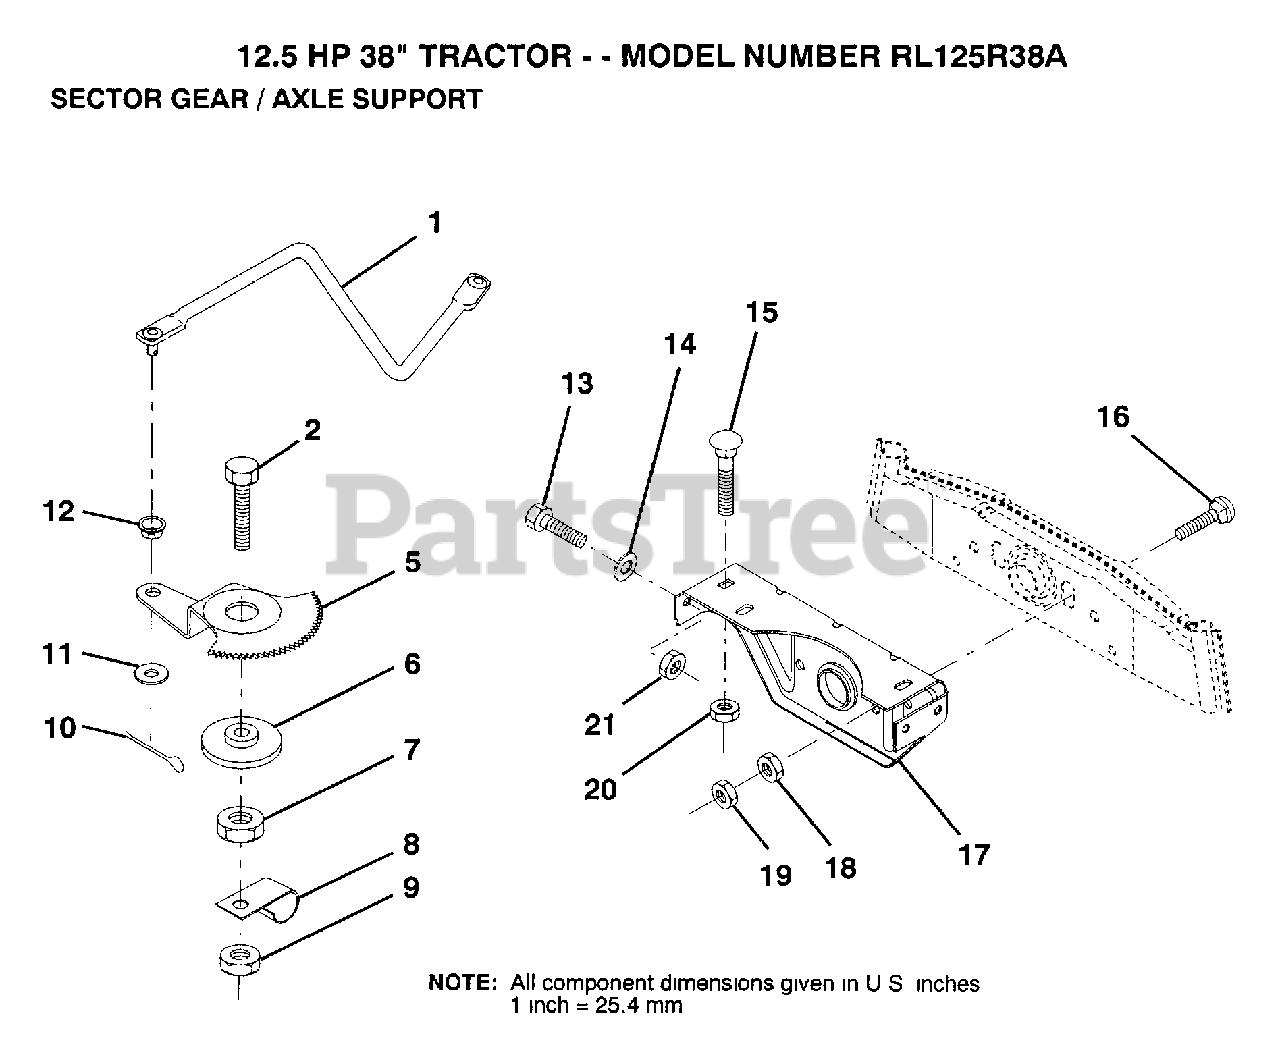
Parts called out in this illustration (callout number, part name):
1	DRAG LINK
2	"BOLT,HEX"
5	GEAR SECTOR
6	BUSHING
7	NUT
8	CLIP INSULATOR
9	NUT LTV
10	COTTER PIN
11	WASHER
12	BUSHING.DRAGLINK
13	BOLT
14	WASHER
15	BOLT
16	BOLT
17	"SUPT,FRT AXLE"
18	NUT.HEX.3/8-16UNC
19	LOCKNUT
